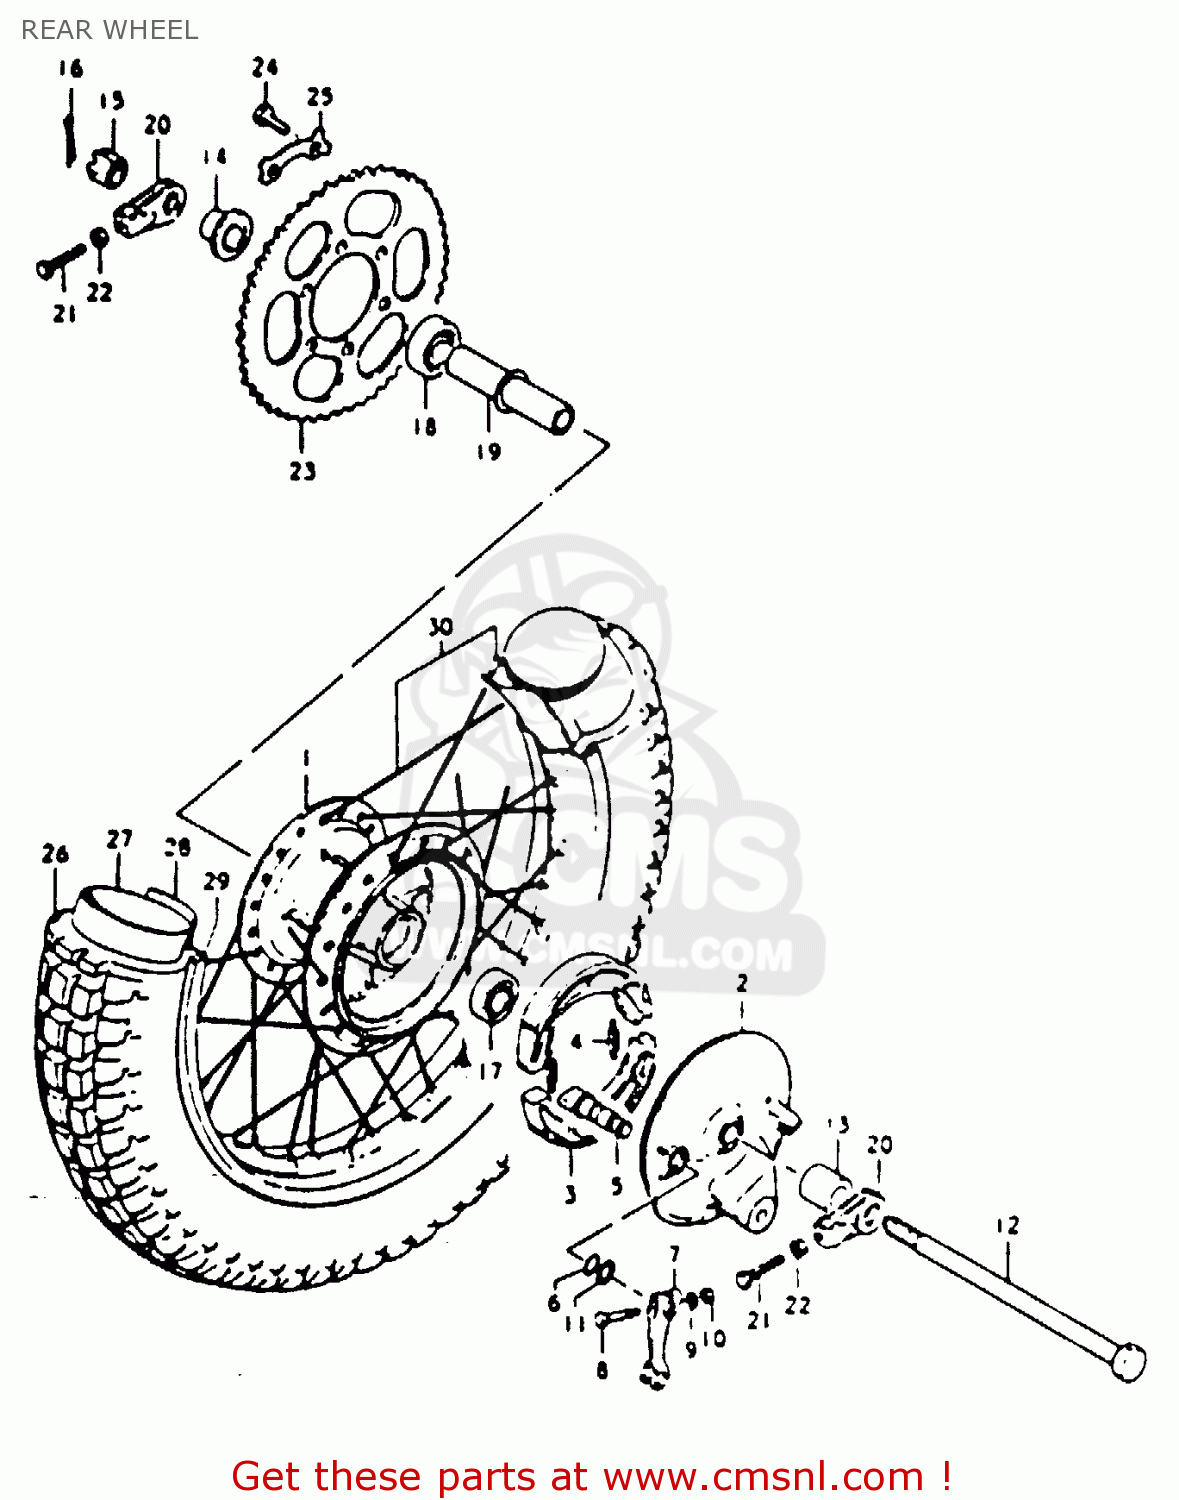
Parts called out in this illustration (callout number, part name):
1	HUB,REAR WHEEL
2	PANEL,RR BRAKE ANCHOR
3	SHOE,BRAKE
4	SPRING(L:34)
5	CAM,FRONT BRAKE
6	O-RING (D:2.4 ID:13.8)
7	LEVER,RR BRAKE CAM
8	BOLT(6X33)
9	WASHER
10	NUT
11	WASHER (14.5X22X1.6)
12	AXLE,REAR
13	SPACER(15.2X22X26)
14	SPACER,RR AXLE,L
15	NUT
16	COTTER PIN
17	BEARING
18	BEARING
19	SPACER,RR WHEEL HUB BEARING
20	ADJUSTER,CHAIN
21	BOLT(8X40)
22	NUT
23	SPROCKET,REAR
24	BOLT(8X30)
25	WASHER
26	TIRE
27	TUBE ASSEMBLY,WHEEL,INNER
28	PROTECTOR,INNER TUBE
29	RIM,REAR WHEEL
30	SPOKE SET
